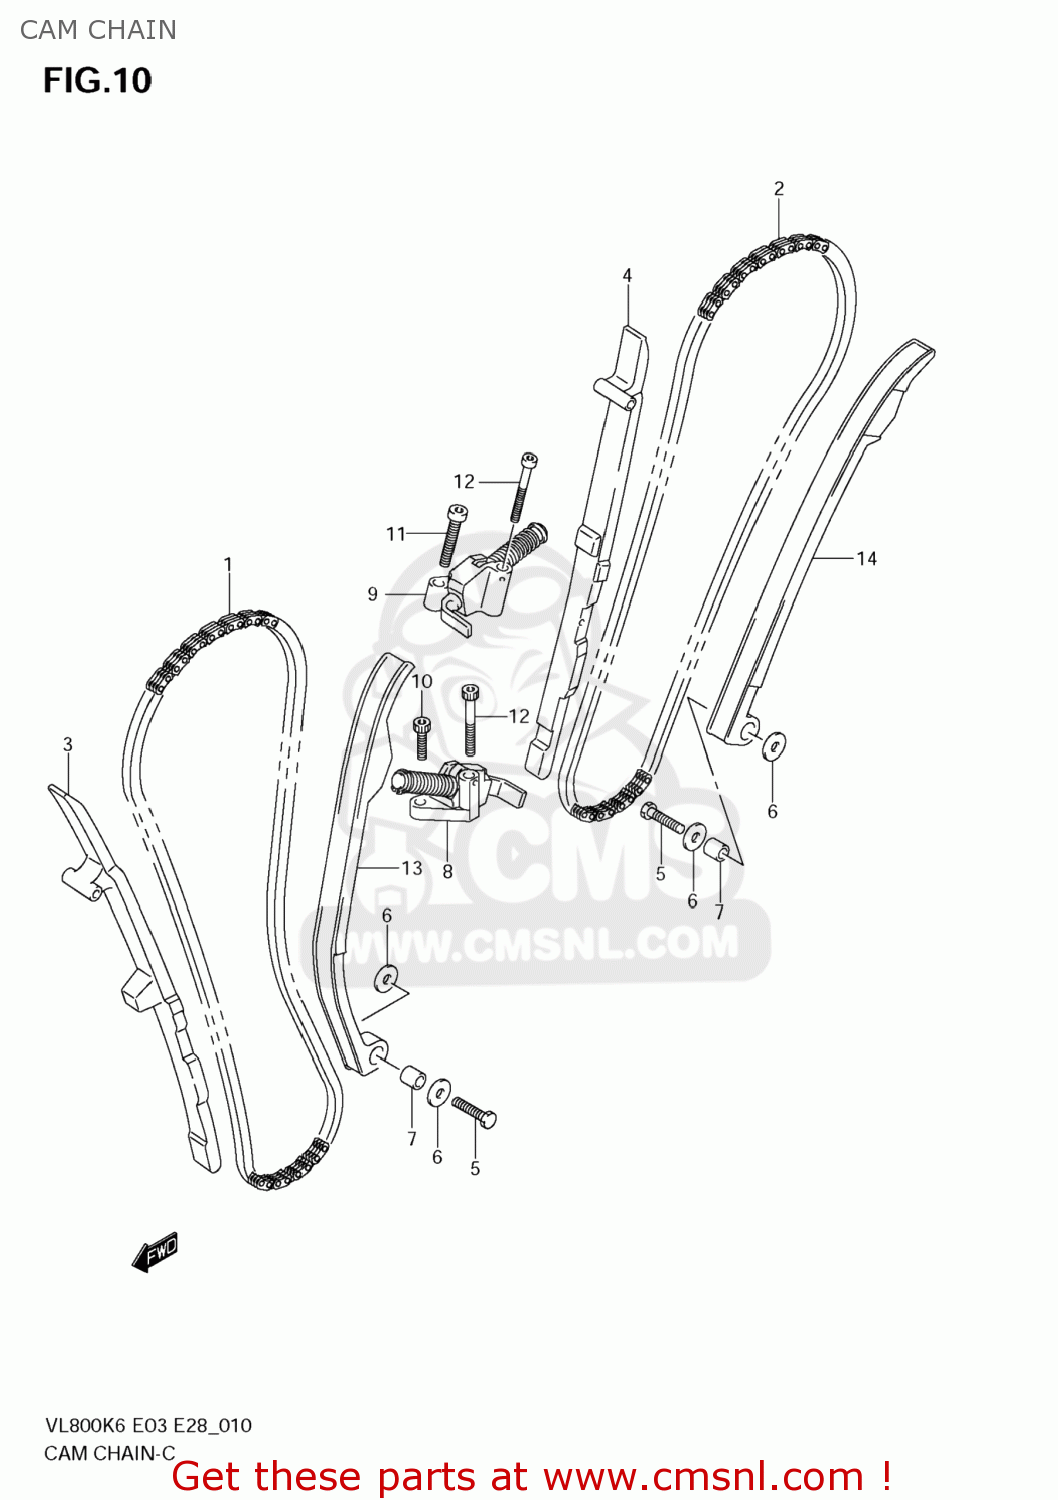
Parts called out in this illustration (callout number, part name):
1	CHAIN CAMSHAFT
2	CHAIN COMP,CAMSHAFT DRIVE
3	GUIDE,CAM CHAIN
4	GUIDE,CAM CHAIN RR
5	BOLT(6X26)
6	WASHER
7	SPACER(6X11X11)
8	ADJUSTER ASSY,FR TENSIONER
9	ADJUSTER ASSY,TENSIONER RR
10	BOLT
11	BOLT
12	BOLT
13	TENSIONER,CAM CHAIN
14	TENSIONER,RR CAM CHAIN
